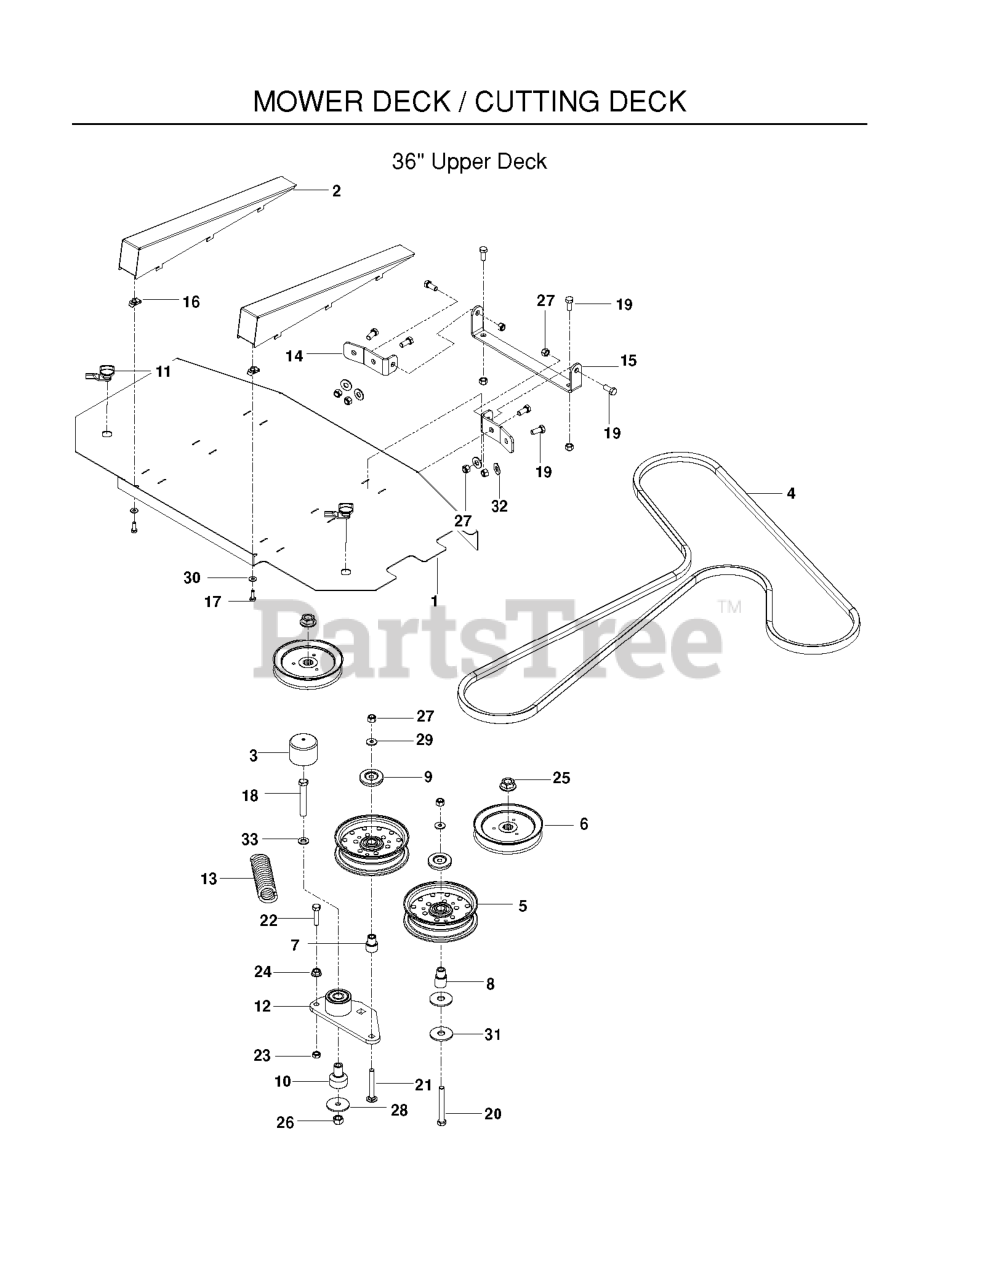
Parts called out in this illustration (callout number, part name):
1	COVER - BELT, 36 PAINTED
2	WEDGE - PAINTED
3	CAP, VINYL
4	BELT - DECK 36 (103 L)
5	IDLER PULLEY
6	PULLEY - 6.57
7	BUSHING, IDLER
8	IDLER BUSHING
9	DUST SHIELD
10	PIVOT, BEARING
11	LATCH, SHORT WING
12	ARM-IDLER W/BRG
14	HINGE, BIN
15	BASE HINGE - PAINTED
16	1/4C - U TYPE RETAINER
17	HCS 1/4C X 3/4 HCS
18	HCS 1/2C X 3 1/4
19	HCS 3/8-16 X 7/8 GR 5 ZD
20	HCS 3/8C X 3
21	RHSNB 3/8-16 X 2.75
22	HCS 3/8-16 X 1-1/2
23	NUT 3/8-16 HEX JAM
24	NUT 3/8C WHIZ
25	NUT FLANGE 3/4-16
26	NUT 1/2-13 HEX NYLOC ZD
27	NUT 3/8-16 NYLOC
28	WASHER, SUPPORT
29	WASHER, 3/8 THICK
30	WASHER 1/4 SAE
31	SPINDLE WASHER
32	WASHER 3/8 FLAT
33	CONTACT BELLSPR 1/2
